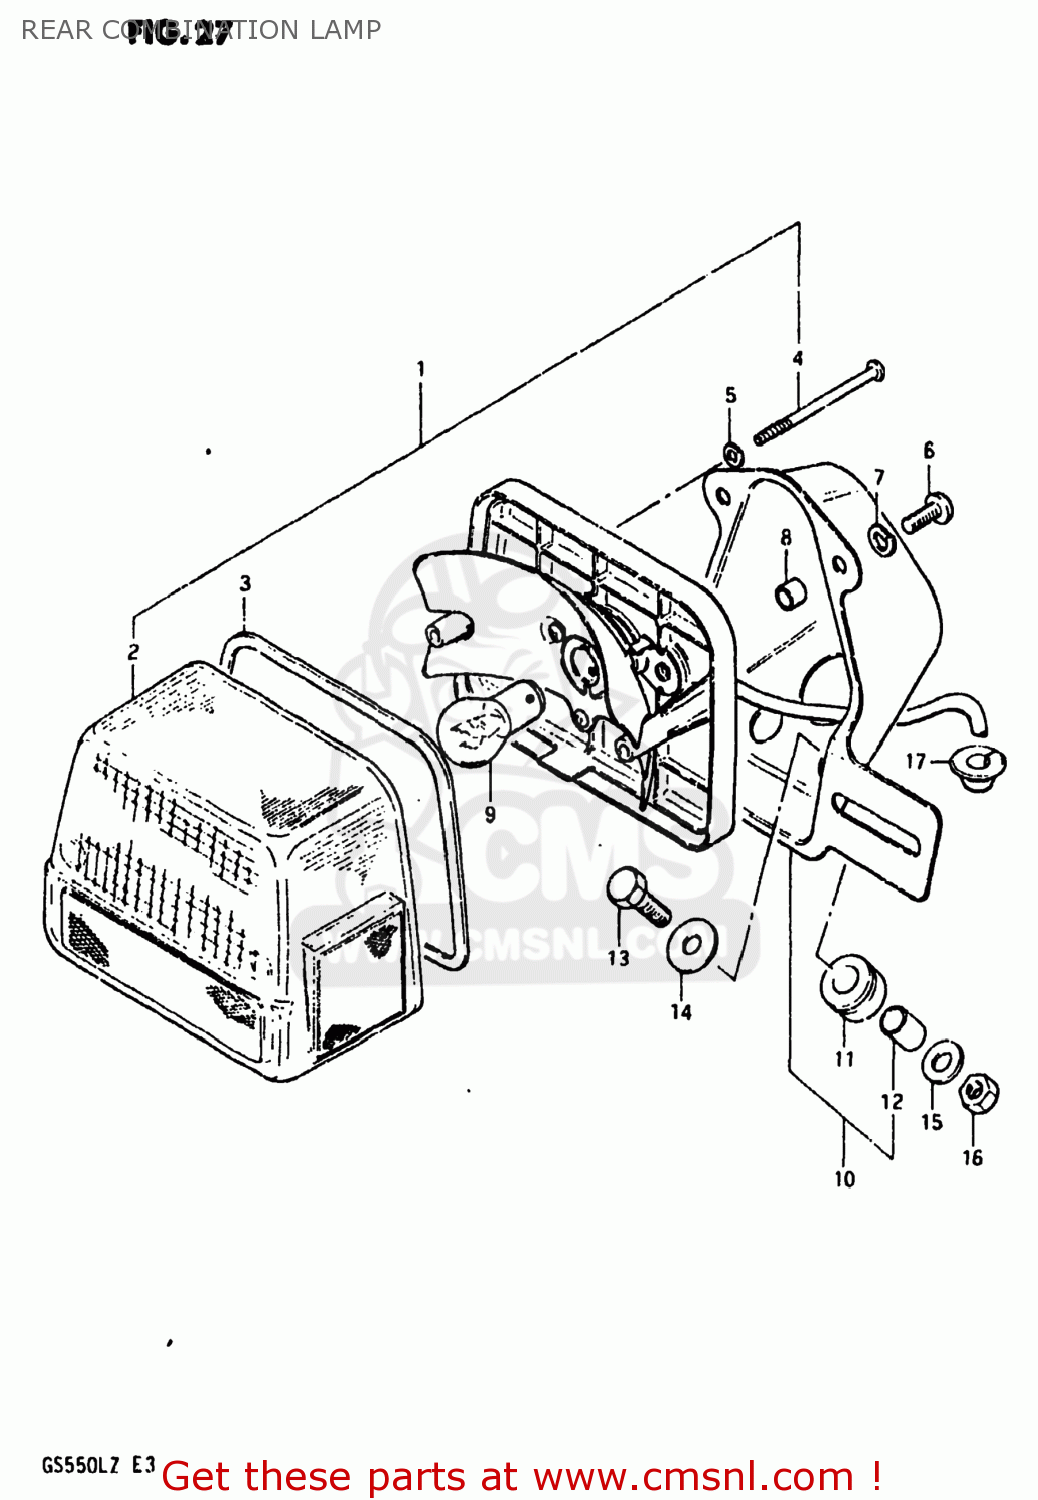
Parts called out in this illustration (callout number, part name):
1	LAMP UNIT,RR COMBNATION
2	LENS
3	GASKET (NAS)
4	SCREW
5	GASKET (NAS)
6	SCREW
7	LOCK WASHER
8	SPACER
9	BULB(12V23W)
10	BRACKET UNIT,TAIL LAMP
11	CUSHION
12	SPACER
13	BOLT
14	WASHER (6.5X20X1.2)
15	WASHER
16	NUT
17	GROMMET
